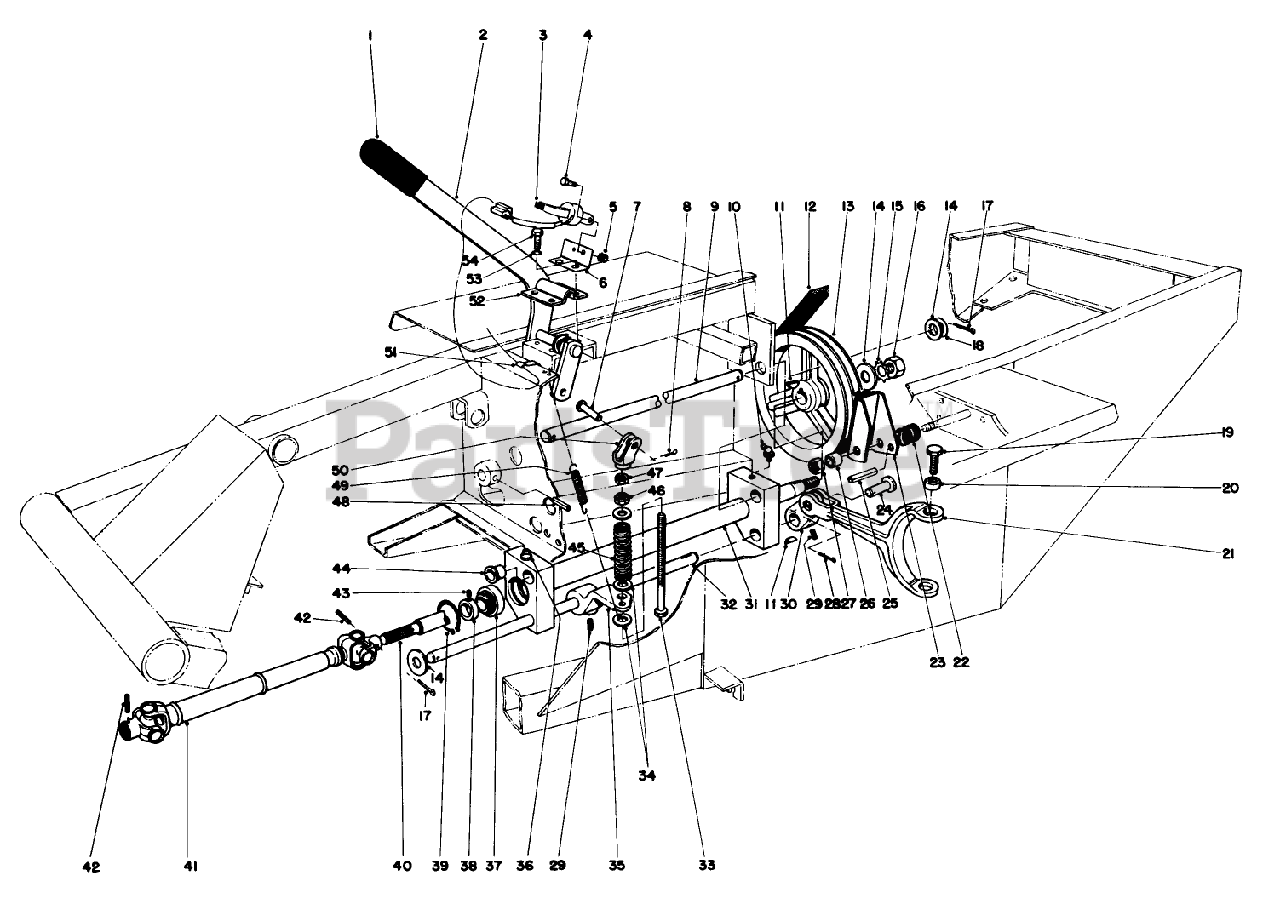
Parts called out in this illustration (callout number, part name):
1	GRIP-HANDLE
2	Lever P.T.O.
3	SWITCH ARM
4	SCREW-HH
5	NUT-LOCK, NI
6	SWITCH ARM MT
7	Clevis Pin
8	PIN-COTTER
9	SHAFT-PIVOT, PTO
10	FITTING-GREASE
11	KEY-WOODRUFF
12	V-Belt
13	PULLEY-PTO
14	WASHER-FLAT
15	WASHER-LOCK, INT
16	NUT-HEX
17	PIN-COTTER
18	WASHER-THRUST
19	BOLT 60368
20	BUSHING PTO FORK
21	FORK PTO B
22	SPRING-ADJUSTMENT
23	PTO BRAKE ASM
24	PIN-CLEVIS
25	PIN-ROLL
26	SPACER-SPRING, ANCHOR
27	NUT-LOCK, NI
28	PIN-COTTER
29	SCREW-HSH
30	PTO ARM
31	Pivot-PTO
32	SHAFT-ACTUATOR, PTO
33	SCREW-ADJUSTING
34	WASHER
35	ARM-ACTUATOR
36	FITTING-GREASE
37	Ball Bearing (Incl. Ref. #38 & 43)
38	Lock Collar (Incl. Ref. #43)
39	RING-SNAP, INTERNAL
40	SHAFT-PTO
41	Universal Joint
42	PIN-ROLL
43	SCREW-SET, HSH
44	BUSHING-FLANGE
45	SPRING-COMPRESSION
46	NUT-LOCK
47	NUT-HEX
48	PIN-ROLL, SLOTTED
49	SPRING-EXTENSION
50	YOKE-PTO
51	CLAMP-CASING
52	CLAMP-LEVER, PTO
53	WASHER-LOCK
54	SCREW-HH, TAP
